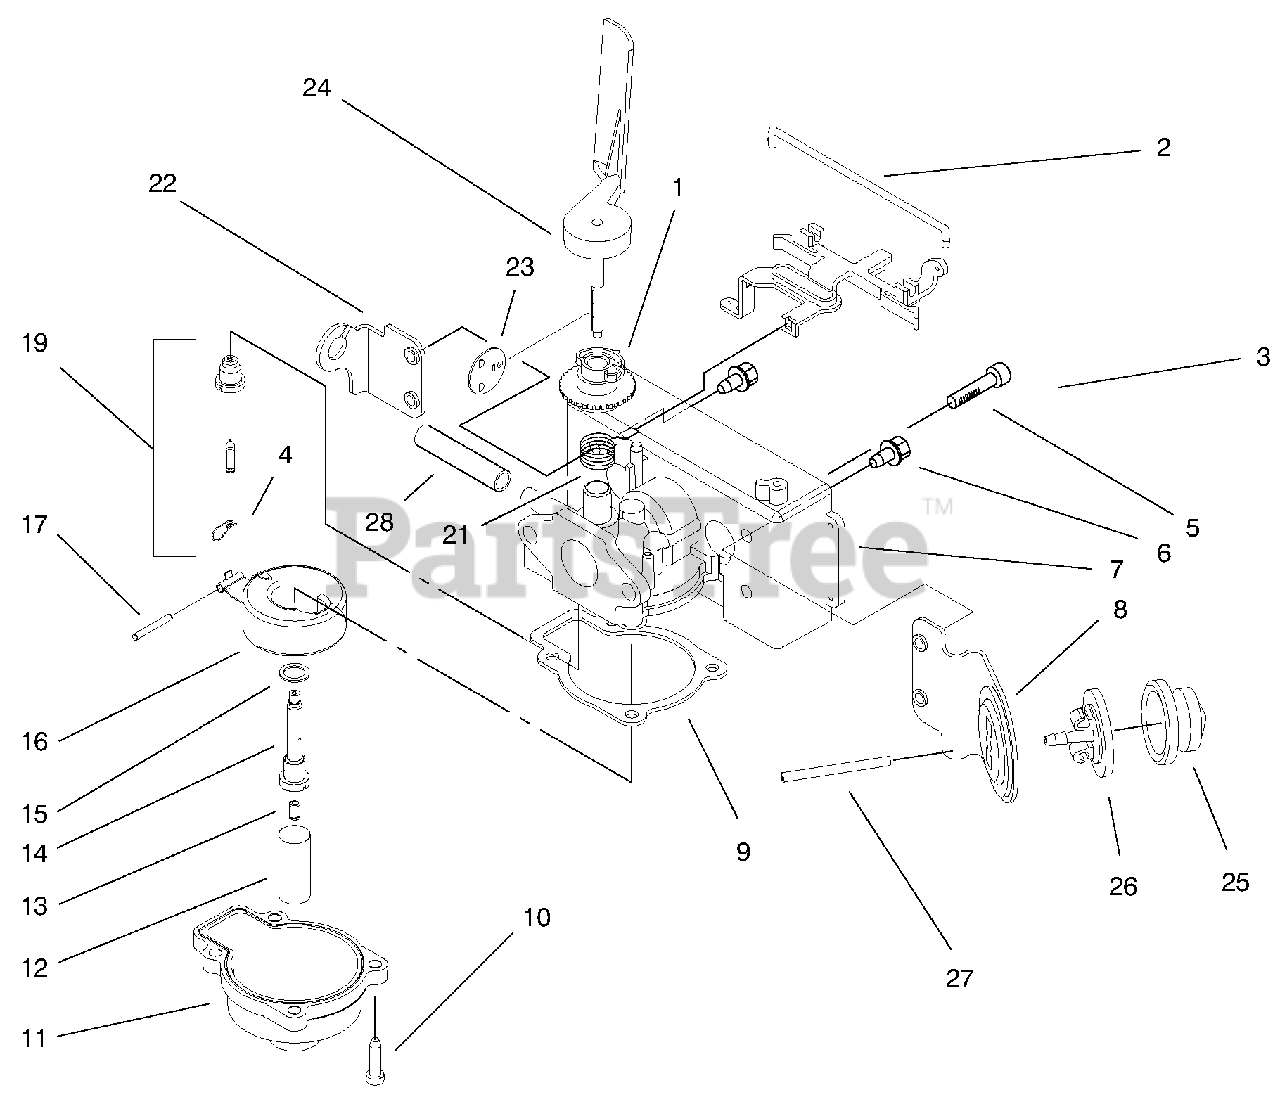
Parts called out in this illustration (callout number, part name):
1	Collar-Adjustment
2	Retainer
3	Lever-Speed Adjust
4	Spring
5	Screw-Pan Hd. Sems
7	Body-Carburetor
8	Bracket-Primer
9	Gasket-Float Chamber
11	Float Chamber
12	Filter-Fuel
13	Main Jet
16	Float & Arm Assembly
19	Float, Valve, & Body Ass'y (Incl. Ref. #4)
21	Spring-Governor
22	Bracket-Throttle Control
23	Disc-Throttle
24	Air Vane & Shaft
25	Bulb-Primer
26	Body-Primer
27	Hose-Primer
28	Line-Gas
